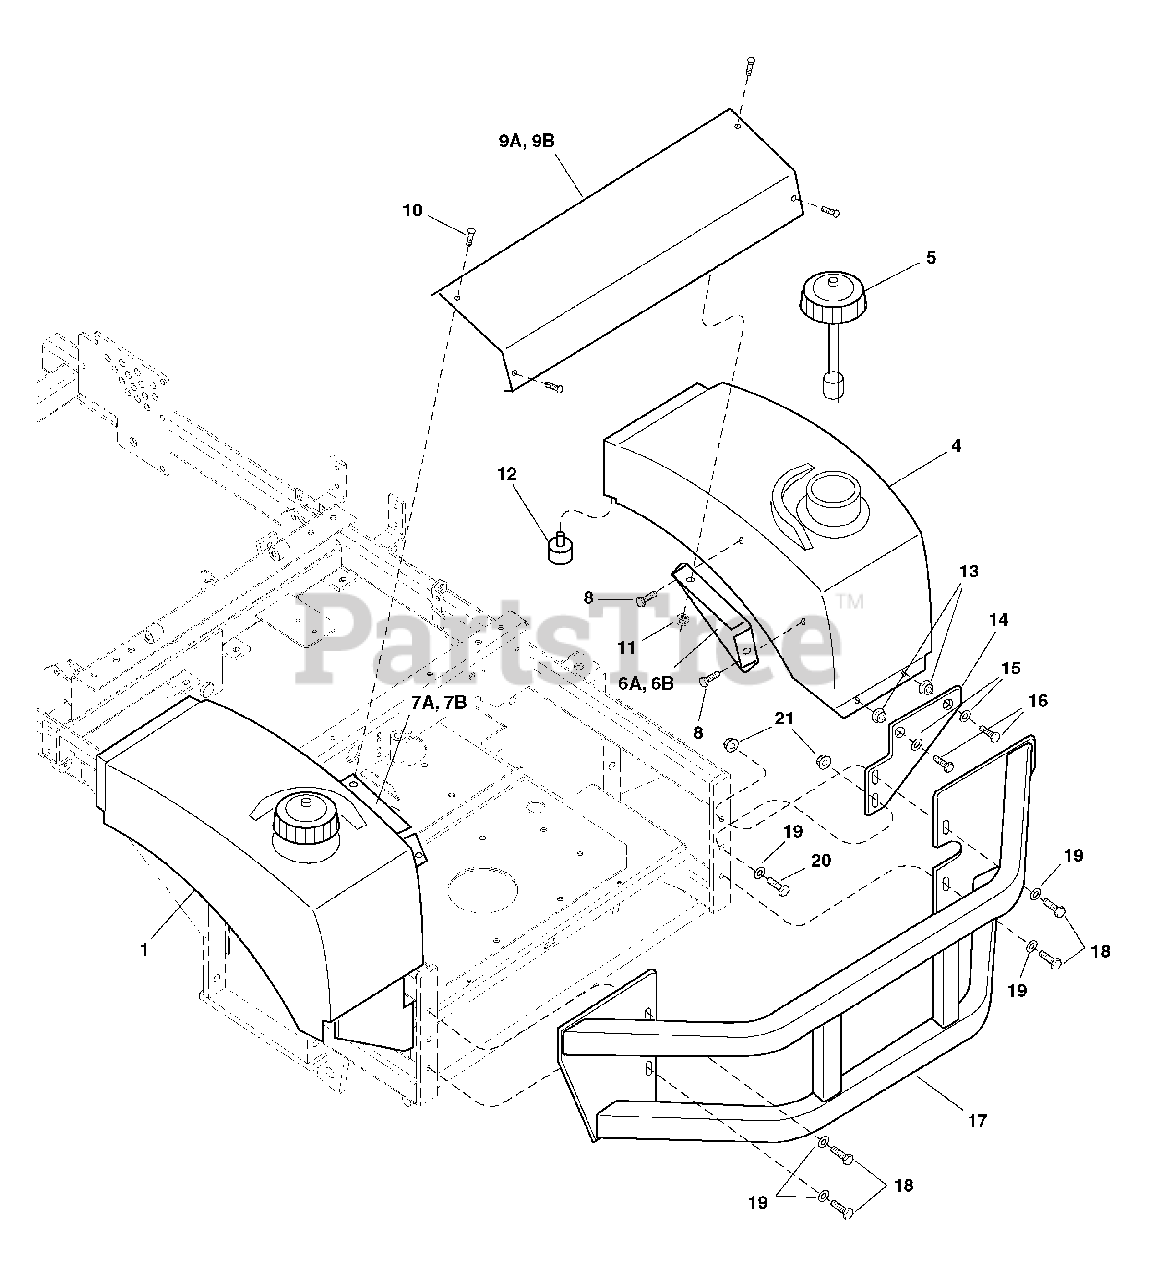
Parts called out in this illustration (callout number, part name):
1	FUEL TANK-LH, Complete (Includes Ref 2 & 3)
4	FUEL TANK-RH, Complete (Includes Ref 2 & 3)
5	CAP, w/ Gauge
6A	MOUNT, Tie Bar-RH (sn: 101-200)
6B	MOUNT, Tie Bar-RH (sn: 201 & up)
7A	MOUNT, Tie Bar-LH (sn: 101-200)
7B	MOUNT, Tie Bar-LH (sn: 201 & up)
8	CAPSCREW, Hex Hd, 5/16-18 x 3/4
9A	FUEL TANK TIE BAR (sn: 101-200)
9B	FUEL TANK TIE BAR (sn: 201 & up)
10	SCREW, Allen Hd, 1/4-20 x 3/4
11	NUT, Hex, Nylon Lock, 1/4-20
12	RUBBER ISOLATOR
13	RUBBER BUSHING
14	FUEL TANK MOUNT PLATE
15	WASHER, 5/16
16	CAPSCREW, Hex Hd, 5/16-18 x 1-1/4
17	BUMPER
18	CAPSCREW, Hex Hd, 3/8-16 x 1-1/4
19	WASHER, 3/8
20	CAPSCREW, Hex Hd, 3/8-16 x 1
21	NUT, Hex, Serrated Flange, 3/8-16
